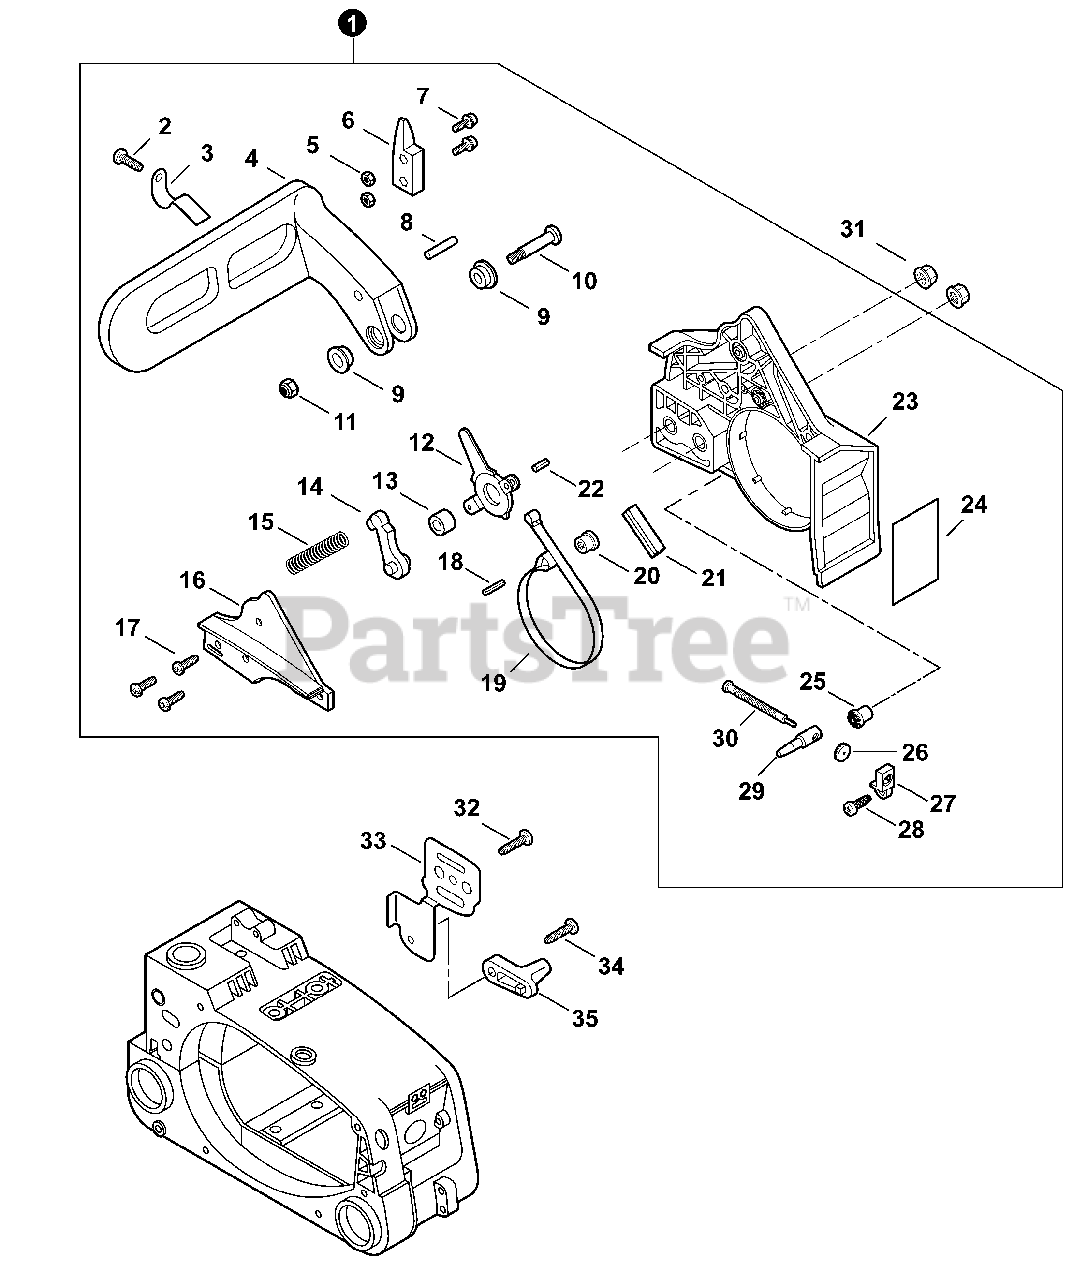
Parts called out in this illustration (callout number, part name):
1	CHAIN BRAKE ASSY
2	SCREW 4×10
3	SPRING, FLAT
4	LEVER, BRAKE
6	WEIGHT, BRAKE
7	SCREW 4×20
8	ROLLER 4×23.8
9	COLLAR 5.3×10×13×L5
10	SCREW 5×32
11	NUT, LOCK M5
12	LEVER, BRAKE
13	SPACER 8×12×9
14	STOPPER, BRAKE
15	SPRING, COMPRESSION
16	COVER, BRAKE
17	SCREW 4×12
18	PIN, SPRING 2.5×12
19	BAND, BRAKE
20	ADJUSTER, BRAKE
21	SEAL, BRAKE
22	PIN, SPRING 4×8.8
23	GUARD, SPROCKET
24	SHIELD, HEAT 35×60×0.10
25	GEAR, BEVEL
26	GEAR, BEVEL
27	COLLAR 8
28	SCREW 4×12
29	TENSIONER, CHAIN
31	NUT, FLANGE M6
32	SCREW 4×10
33	PLATE, GUIDE
34	SCREW, TAPPING 5×20
35	CHAIN CATCHER
